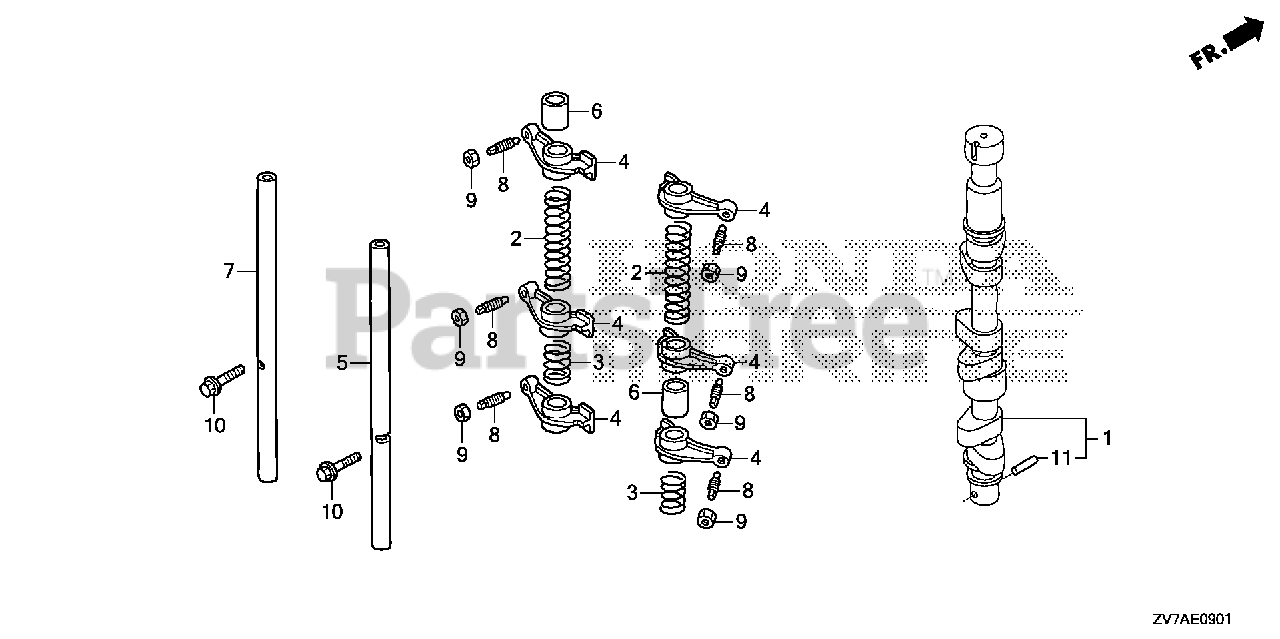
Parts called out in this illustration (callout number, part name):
2	SPRING, ROCKER ARM A
3	SPRING, ROCKER ARM B
4	ARM, VALVE ROCKER
5	SHAFT, IN. ROCKER ARM
6	COLLAR, ROCKER
7	SHAFT, EX. ROCKER ARM
8	SCREW, TAPPET ADJUSTING
9	NUT, TAPPET ADJUSTING
10	BOLT, FLANGE (6X28)
11	ROLLER (3X16.8)
